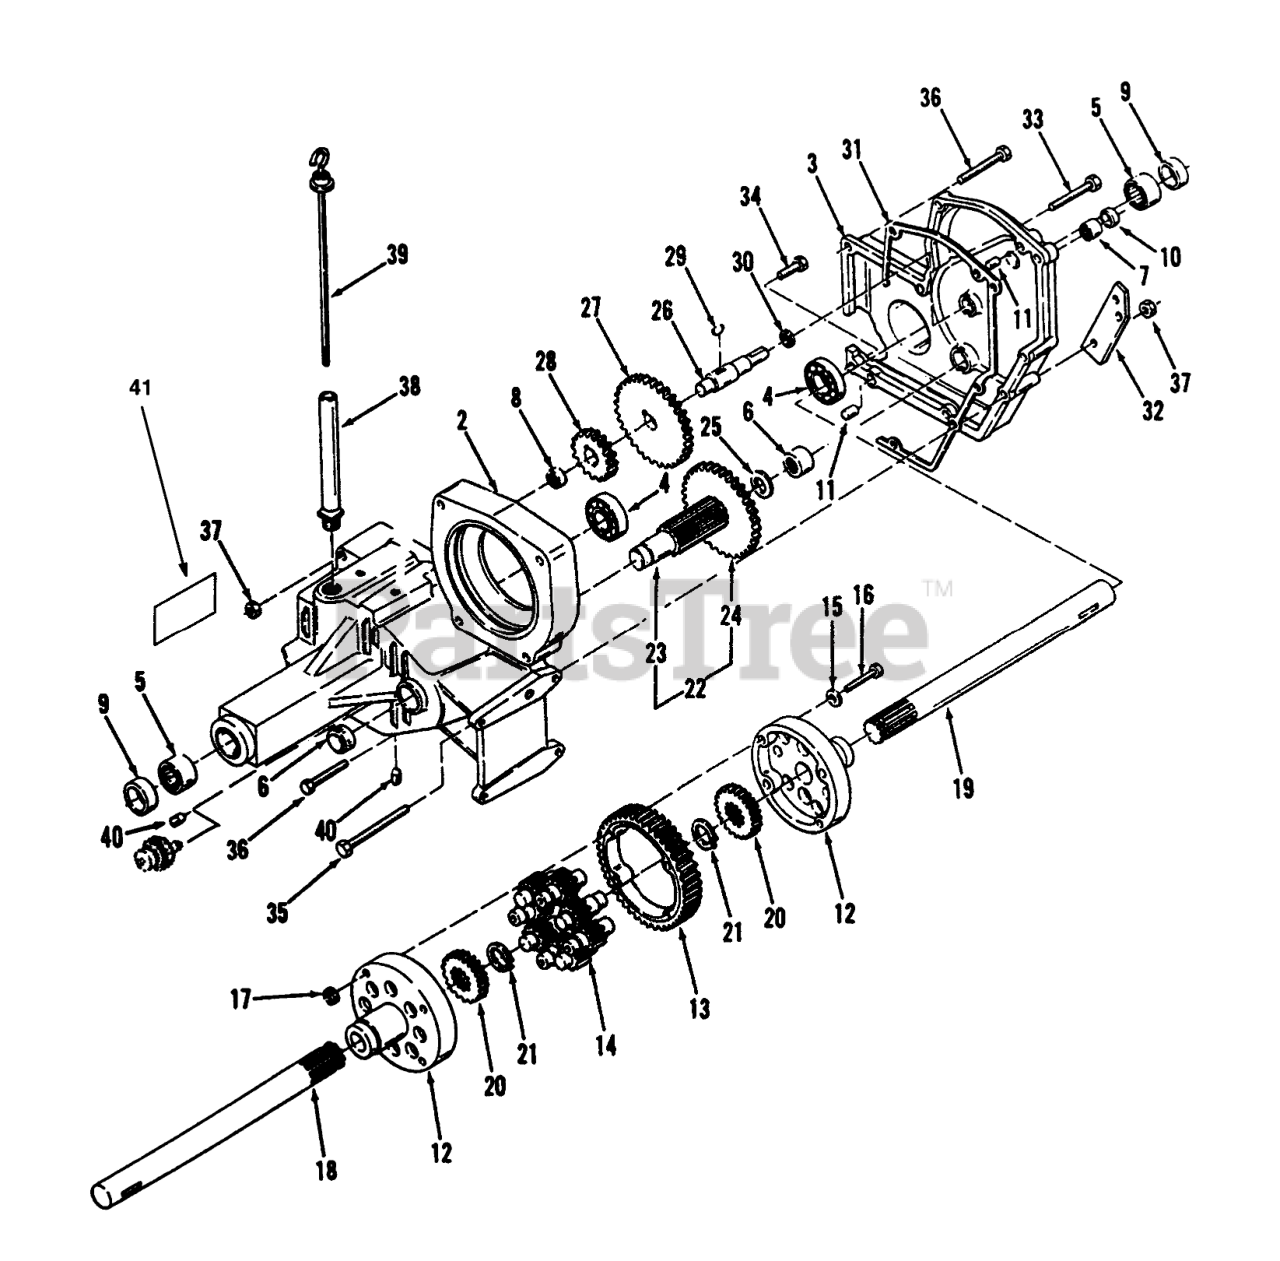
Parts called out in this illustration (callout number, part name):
1	Transaxle-Complete (Incl. Ref. #41)
2	Case-Transaxle, RH (Incl. Ref. #41)
3	CASE TRANS LH
4	BEARING-BALL
5	BEARING
6	BEARING-NEEDLE
7	NEEDLE BEARING
8	BEARING-NEEDLE
9	SEAL-OIL
10	Seal
11	PIN-LOCATING
12	END CAP-DIFFERENTIAL
13	GEAR-DIFFERENTIAL RING, 43T
14	GEAR-PINION, 11T
15	WASHER
16	BOLT-HEX
18	AXLE-REAR RH
19	AXLE-REAR LH
20	GEAR-AXLE DIFFERENTIAL
21	RING-SNAP
22	ASSY GEAR
23	PINION SHAFT
24	GEAR 46T
25	WASHER-THRUST
26	SHAFT GEAR
27	GEAR 46 TEETH
28	GEAR 20 TEETH
29	WOODRUFF KEY
30	Race Thrust
31	GASKET-TRANSMISSION
32	BRACKET-BRAKEB
33	SCREW-HH
34	SCREW-HH
35	SCREW-HH
36	SCREW-HH
37	NUT-LOCK, NI
38	NIPPLE-TRANS FILL
39	Dipstick
41	DECAL - DANGER
